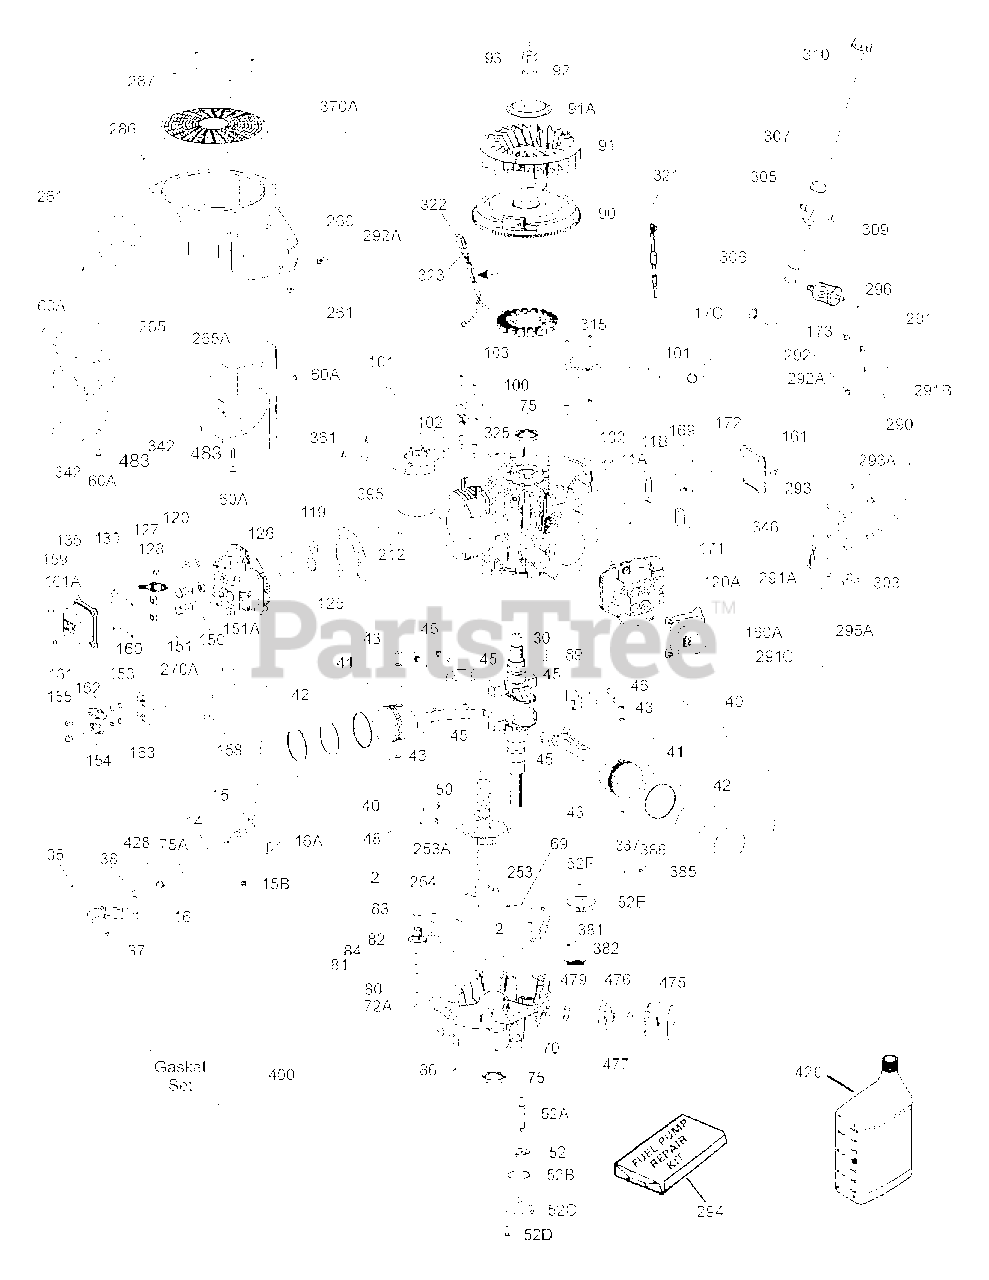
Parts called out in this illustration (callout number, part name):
11A	Breather Plate
11B	Screw, 10-32 x 7/16"
15	Governor Rod
15B	Screw, 1/4-20 x 5/8"
16	Governor Lever
16A	Governor Spring Bracket
17C	Breather Tube Clamp
35	Screw, Carriage 1/4-20 x 1-1/2"
37	Lock Nut, 1/4-20
38	Retaining Ring
40	Piston, Pin & Ring Set (Std.)
40	Piston, Pin & Ring Set (.010" OS)
41	Piston & Pin Ass'y. (Std.)
41	Piston & Pin Ass'y.(.010" OS)
42	Ring Set (Std.)
42	Ring Set (.010" OS)
43	Piston Pin Retaining Ring
45	Connecting Rod Ass'y.
46	Connecting Rod Bolt
50	Camshaft (MCR)
52	Oil Pump Ass'y.
52A	Oil Pump Shaft
52C	Oil Pump Cover
52D	Screw, T-30 1/4-20 x 43/64"
52E	Oil Pump Gear
52F	Oil Pump Gear Retaining Ring
60A	Screw, 1/4-20 x 1/2"
69	Mounting Flange Gasket
70	Mounting Flange
75	Oil Seal (1 in Ref 1, 1 in Ref 70)
75A	Oil Seal (Governor Shaft)
80	Governor Shaft
81	Washer (Governor Shaft)
82	Governor Gear Ass'y.
83	Governor Spool
84	Retaining Ring
86	Screw, 5/16-18 x 1-15/32"
90	Flywheel
91	Flywheel Fan
91A	Flywheel Retainer
92	Belleville Washer
100	Solid State Ignition
101	Spark Plug Cover
102	Solid State Mounting Stud
103	Screw, T-15 10-24 x 15/16"
119	Cylinder Head Gasket
120	Cylinder Head, Opp. Breather Side
120A	Cylinder Head, Breather Side
125	Exhaust Valve (Std.)
126	Intake Valve (Std)
128	Belleville Washer
130	Screw, 5/16-18 x 2-1/2" (Head Mount)
135	Spark Plug (RN4C)
150	Valve Spring
151	Valve Keeper Retainer & Cap Set
153	Push Rod Guide
154	Rocker Arm Stud
159	Rocker Arm Cover Gasket
160	Rocker Arm Cover, Opp. Breather Side
160A	Rocker Arm Cover, Breather Side
161	Screw, T-30 1/4-20 x 1/2"
162	Rocker Arm Jam Nut, 5/16-24
163	Internal Lock Washer, 5/16"
169	Valve Cover Gasket
171	Breather Element
173	Breather Tube
253	Compression Release Weight
253A	Compression Release Pin
254	Compression Release Spring
260	Blower Housing (Red)
261	Screw, 1/4-20 x 1/2"
265	Cylinder Head Cover, Opp. Breather
265A	Cylinder Head Cover, Breather Side
270A	Exhaust Port Liner
286	Flywheel Screen
287	Screw, T-20 8-18 x 1-15/32"
290	Fuel Line (16.75")
291	Fuel Line (8-1/4")
291A	Fuel Line (8-1/4")
291C	Fuel Line (6.75")
292	Fuel Line Clamp
292A	Fuel Line Retainer
293	Pulse Pump
293A	Screw, 8-32 x 1-1/2"
295A	Fuel Fitting
296	Fuel Filter
303	Pulse Pump/Fuel Fitting
305	Oil Fill Tube
306	O-Ring (Oil Fill, Bottom)
309	Screw, 1/4-20 x 57/64"
315	Alternator Coil (16 Amp)
322	Connector Body
342	Screw, 1/4-20 x 9/16"
346	Fuel Pump Bracket
361	Screw, 5/16-18 x 2-3/8"
370A	Lubrication Decal
381	Screw, 8-32 x 27/64"
382	Oil Strainer Screen
386	Pressure Release Spring
395	Electric Starter Motor (12 Volt)
400	Gasket Set
476	Oil Filter Adaptor
477	Screw, T-30 5/16-18 x 1 3/32"
479	Oil Filter Adaptor Gasket
483	Cylinder Wrap Spacer
